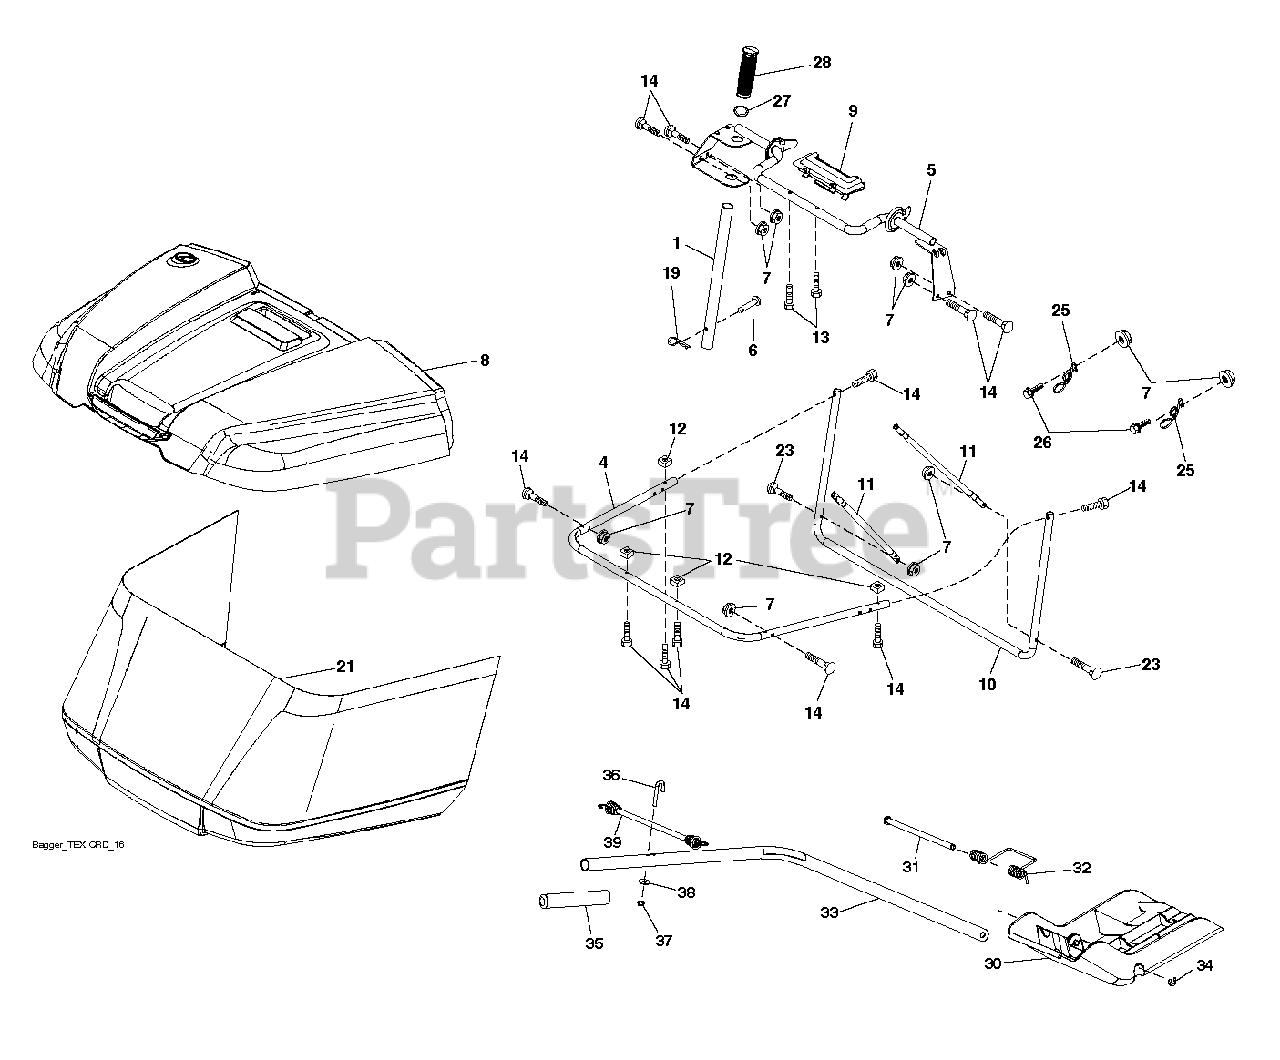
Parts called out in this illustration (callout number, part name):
1	TUBE.PNT.HDL.BAGGER.
6	RIVET,DRILLED
7	NUT T
19	PIN.COTTER.5/16.BOW TI
26	SCREW HEX CRT
28	GRIP.HANDLE.BLACK
34	E-RING.5/16"
38	WASHER
